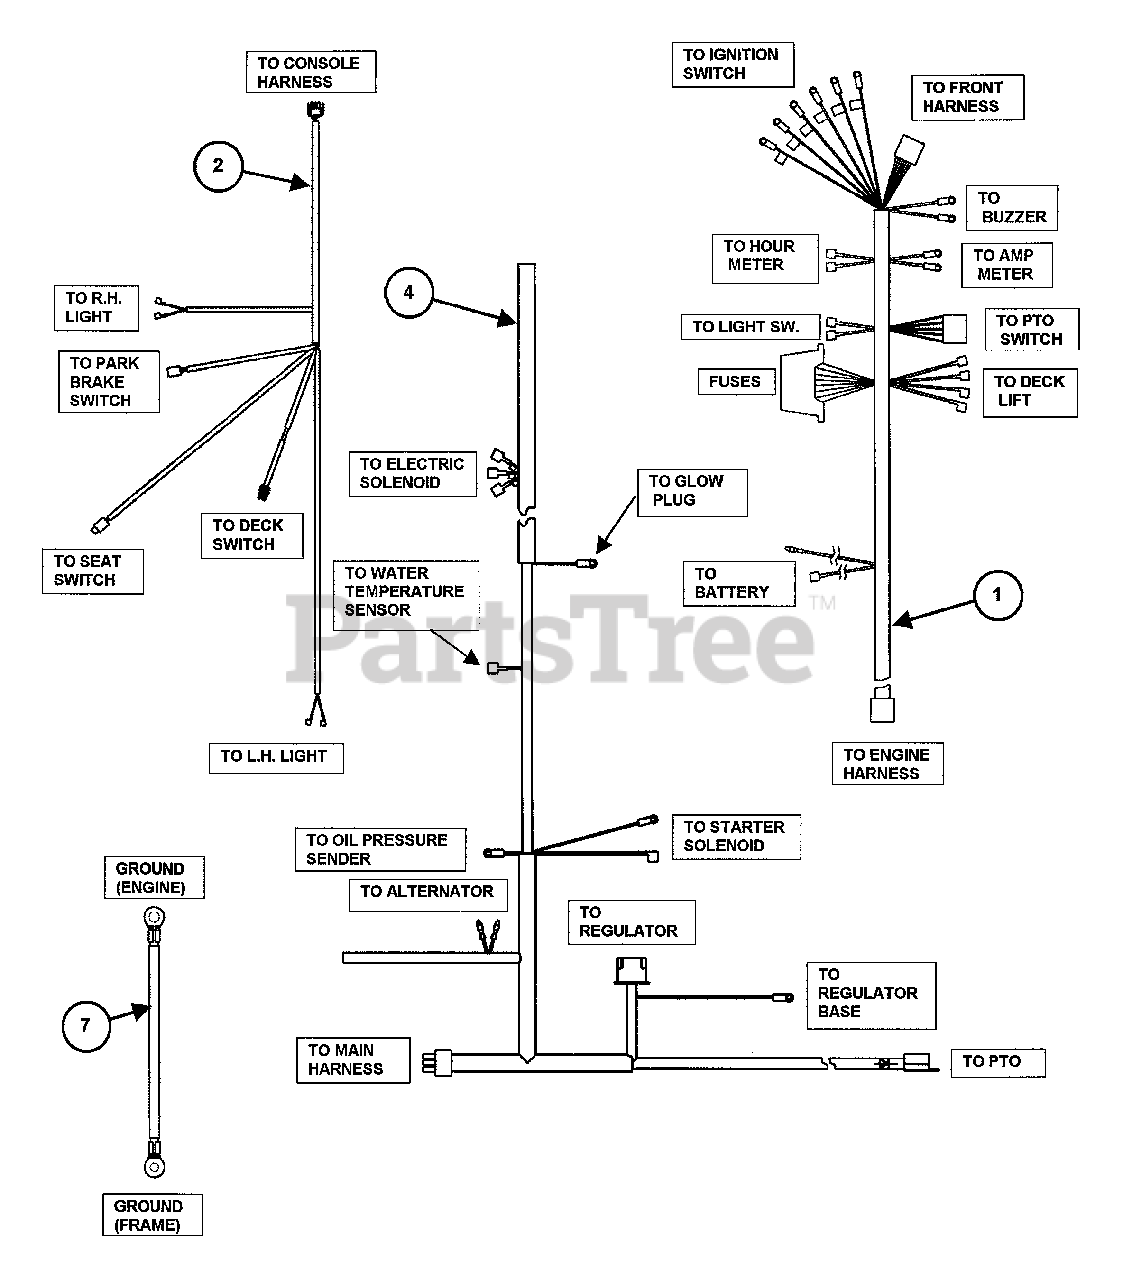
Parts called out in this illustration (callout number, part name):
1	HARNESS, Control Panel
2	HARNESS, Front
3	HARNESS, Deck Lift (15" Long)
4	HARNESS, Engine (Kubota D722)
5	CABLE, Battery-Positive (51" Long)
6	CABLE, Battery-Ground (38" Long)
7	CABLE, Chassis-Ground (15" Long)
